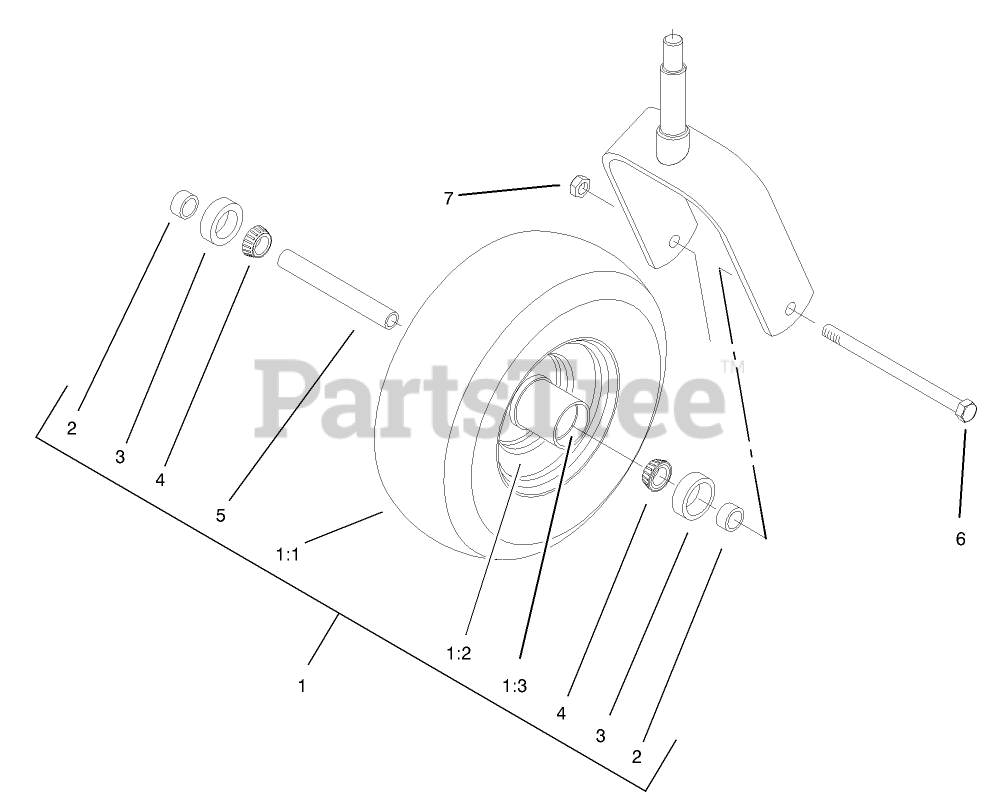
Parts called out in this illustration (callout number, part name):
1	WHEEL and TIRE ASM
1:3	BEARING-CUP
2	SPACER-BEARING
3	SEAL-BEARING
4	BEARING-CONE, TAPER
5	SPACER-CASTER, FRONT
6	SCREW-HH
7	NUT-LOCK, NI
